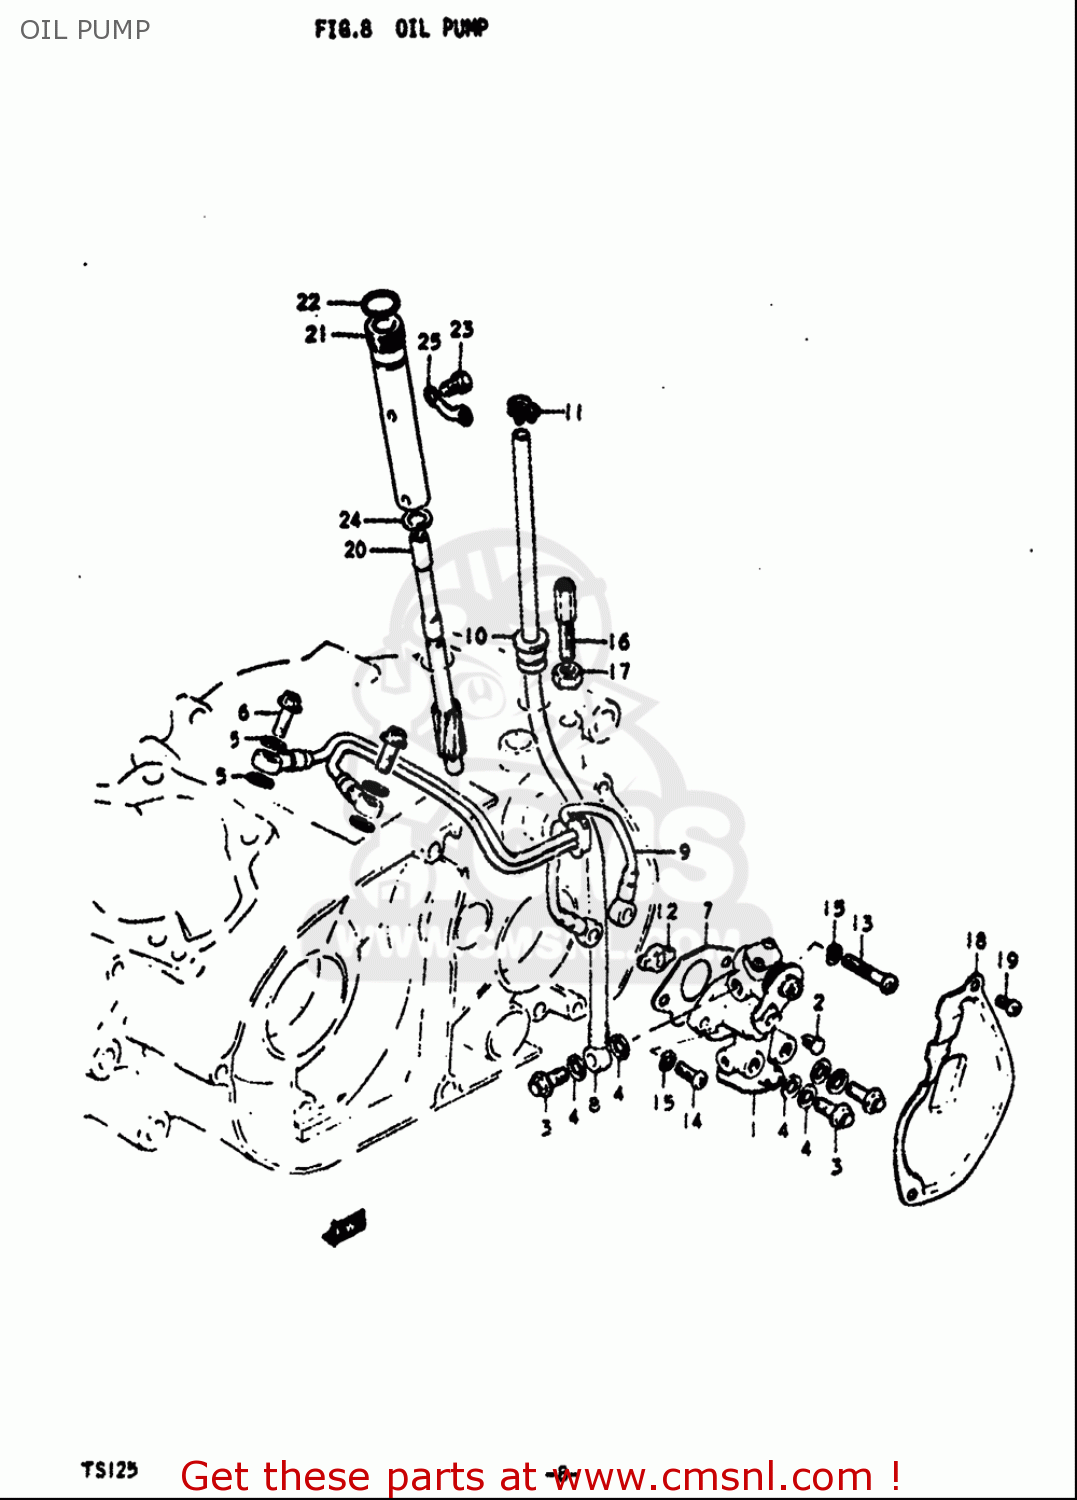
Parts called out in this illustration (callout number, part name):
2	TERMINAL,CABLE
3	UNION BOLT
4	GASKET(6.2X11X1).2 (NAS)
6	UNION BOLT
7	GASKET,OIL PUMP (NAS)
8	HOSE,INLET
11	CLAMP
12	PIECE,OIL PUMP DRIVE
13	SCREW
14	SCREW
15	WASHER,LOCK
16	BOLT
17	NUT
19	SCREW
21	SLEEVE,TACHOMETER DRIVEN GEAR
22	O RING(D:1.3,ID:9.6)
23	BOLT(6X12)
24	WASHER(8X13.7X1)
